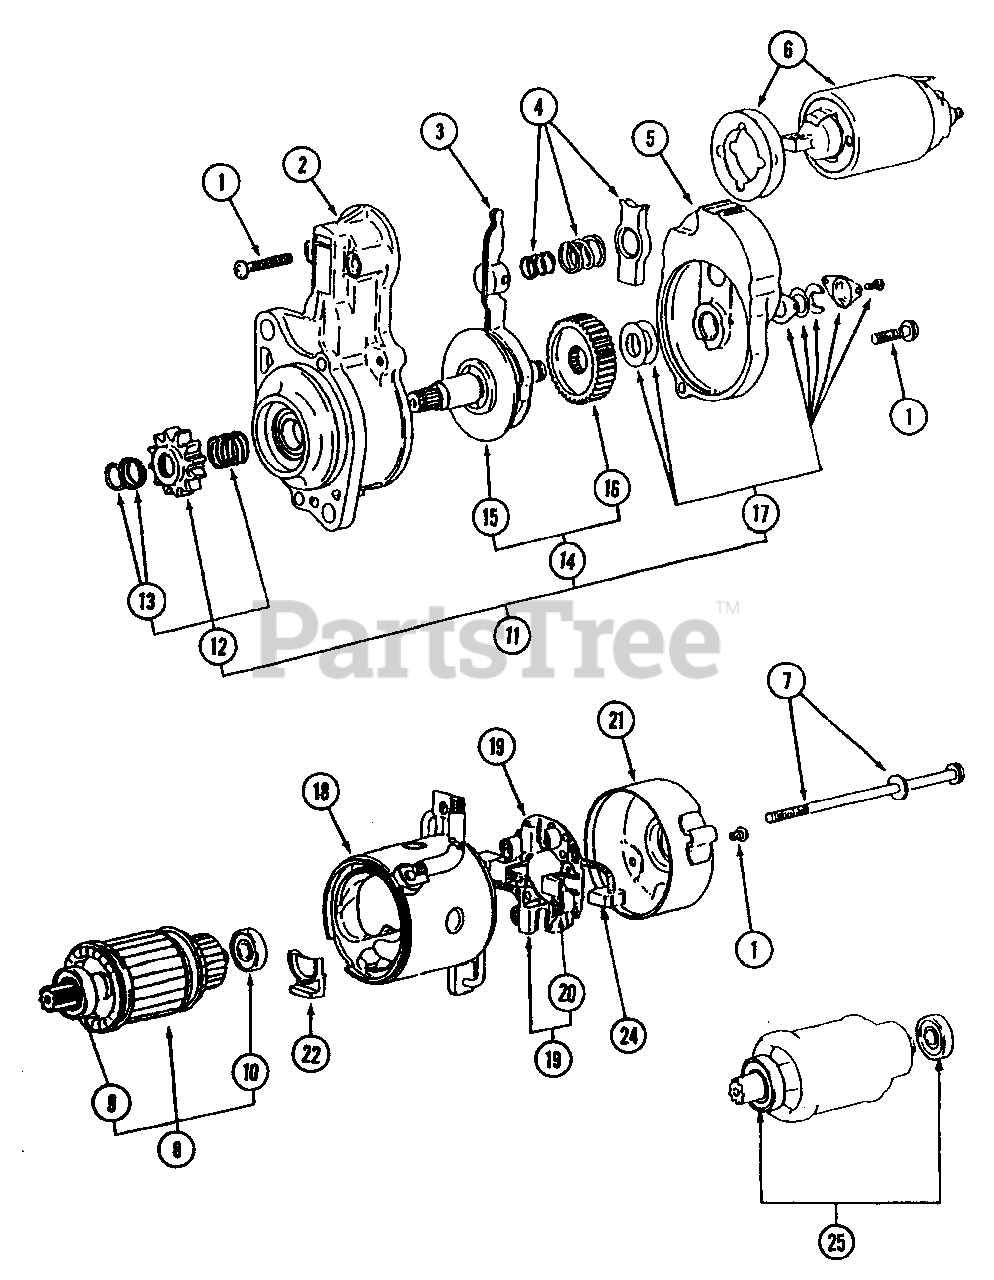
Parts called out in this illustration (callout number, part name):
2	Bracket Ass'y.,Front
3	Lever Ass'y.
4	Spring Set
5	Bracket Ass'y.,Center
6	Switch Ass'y.
8	Armature Set
9	Bearing, Front
10	Bearing, Rear
11	Shaft Ass'y., Clutch Set
15	Shaft Ass'y., Pinion
18	Yoke Ass'y.
19	Holder Ass'y., Brush
20	Spring, Brush
21	Bracket Ass'y., Rear
24	Brush
25	Service Kit
